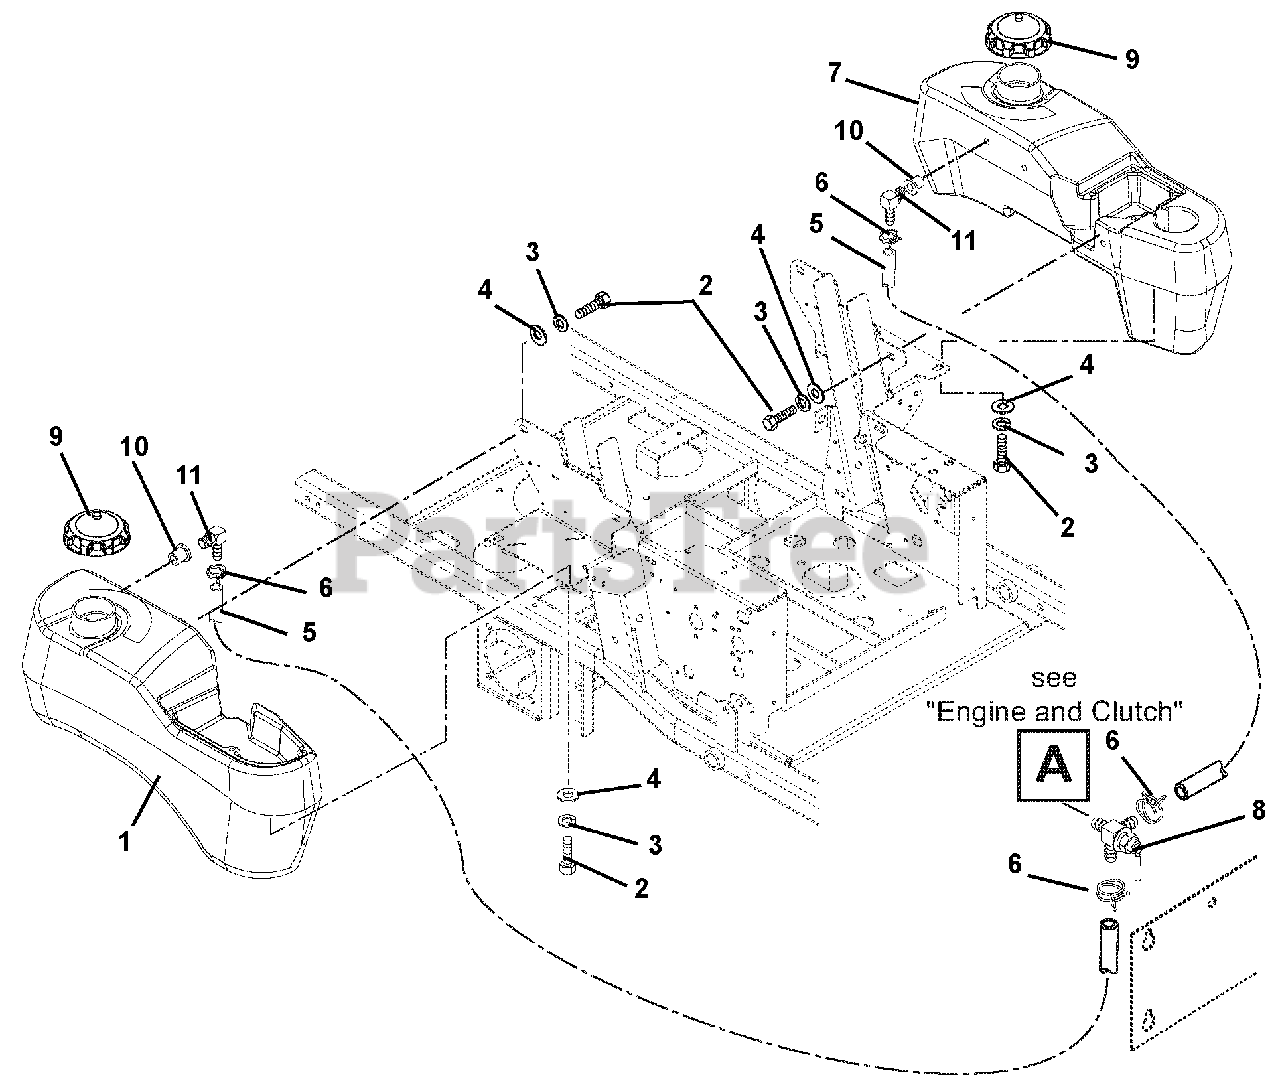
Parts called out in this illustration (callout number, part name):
1	Tank, Fuel - Right Hand
2	Bolt, Hex .31-18 x .75 Grade 5
3	Washer, Locking .31 x .078
4	Washer, Flat Steel .38 x .875 x .083
5	n. Gas Line, Bulk .25 I.D. (2 @ 63 in.)
6	Clamp, Hose Wire .49/.51 x .116
7	Tank, Left Hand Fuel (EYE-Q)- 200 Series
8	Valve, Fuel
9	Cap, Gas
10	Bushing (Black in color. Does not replace or interchange with orange colored grommet)
11	Tank Fitting
